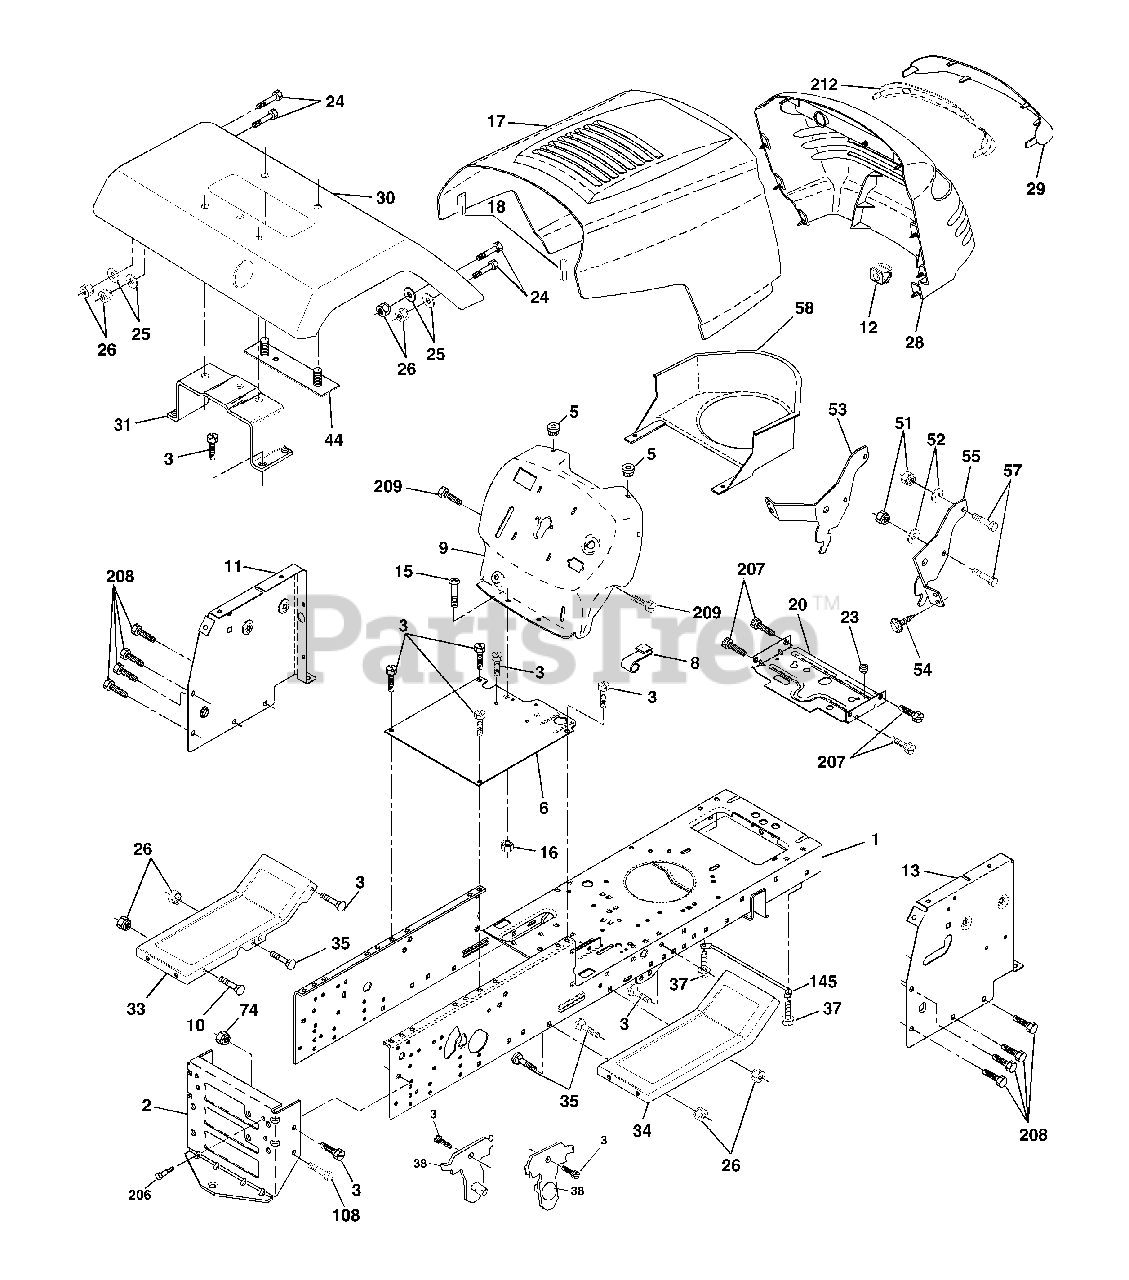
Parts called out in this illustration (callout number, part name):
1	Chassis Wldmt.
2	Drawbar Stretch 94
3	Screw 3/8-16 x 3/4
5	Bumper Hood/Dash
6	Saddle Flat Lt
8	Clip Retainer Slide-On
9	Dash Private Label
10	Bolt Rd Hd Sqnk. 3/8-16 Unc x 1
11	Panel Asm. Dash Lh
12	Clip Tinnerman Grile P/L
13	Panel Dash Rh
15	Screw Mach Trhd 5/16-18 Unc x 3/4
16	Nut Keps 5/16-18 Unc
17	Hood Pnt STL P/L w/trim
18	Bumper Hood
20	Plate Mtg Battery/Fule Tank
23	Bushing Snap Nyl Blk Fuel Line
24	Bolt Fin Hex 3/8-16 Unc x 1 Gr. 5
25	Washer 13/32 x 13/16 x 12 Ga.
26	Nut Lock Hex w/Insert 3/8-16 UNC
28	Grill / Lens Asm
29	Lens Grille Private label
30	Fender Asm YTGT
31	Bracket Fender
33	Footrest Pnt. Lh
34	Footrest Pnt. Rh
35	Bolt Rd Hd Sht. Sqnk. 3/8-16 x 3/4
37	Screw Thdrol 5/16-18 x 1/2 Tyt
38	Bracket Asm Pivot Mower Rear
44	Strap Asm Fender
51	Nut Lock Hex W/Ins. 1/4-20
52	Washer 9/32 x 7/8 x 16 Ga.
53	Bracket Grille LH
54	Screw Hex Wshd 8-18 x 7/8
55	Bracket, Grille RH
57	Bolt Fin Hex 1/4-20 x .75
58	Air Duct Private Label
74	Nut Crownlock 3/8-16 Unc
108	Bolt Fin Hex 3/8-16 Unc x 3/4
145	Rod Pivot Chassis/Hood
206	Bolt Shoulder 5/16-18
207	Screw Thdrol 5/16-18 x 1/2
208	Screw Thdrol 3/8-16 x 1/2
209	Screw Hex wsh Thdrol 3/8-16 x 3/4
212	Insert Lens Reflective
